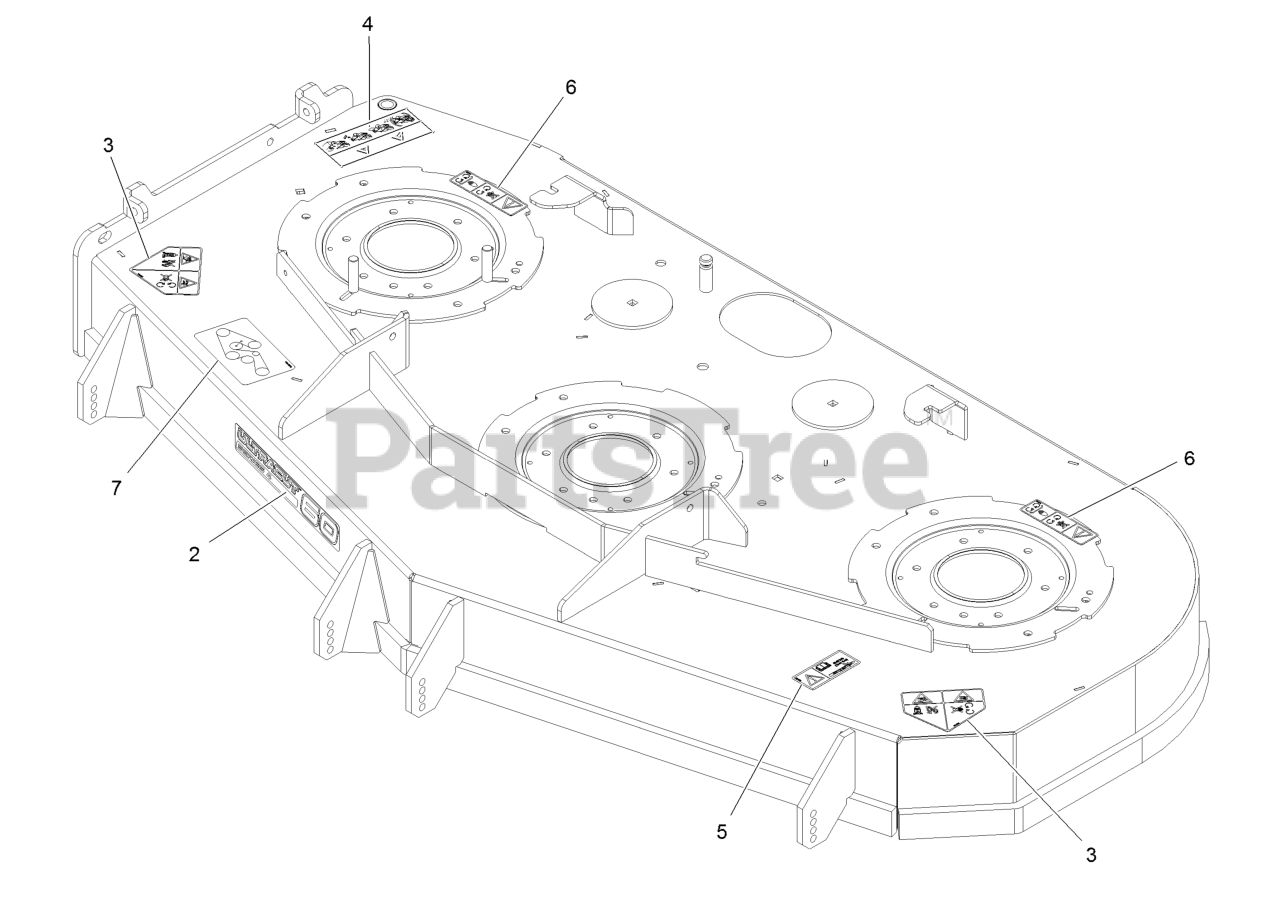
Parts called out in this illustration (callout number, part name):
2	Decal, 604
3	Decal-Danger
4	Decal-Warning, Bagger
5	Decal-Bolt Torque
6	Decal-Cover, Missing
7	Decal-Belt Routing
